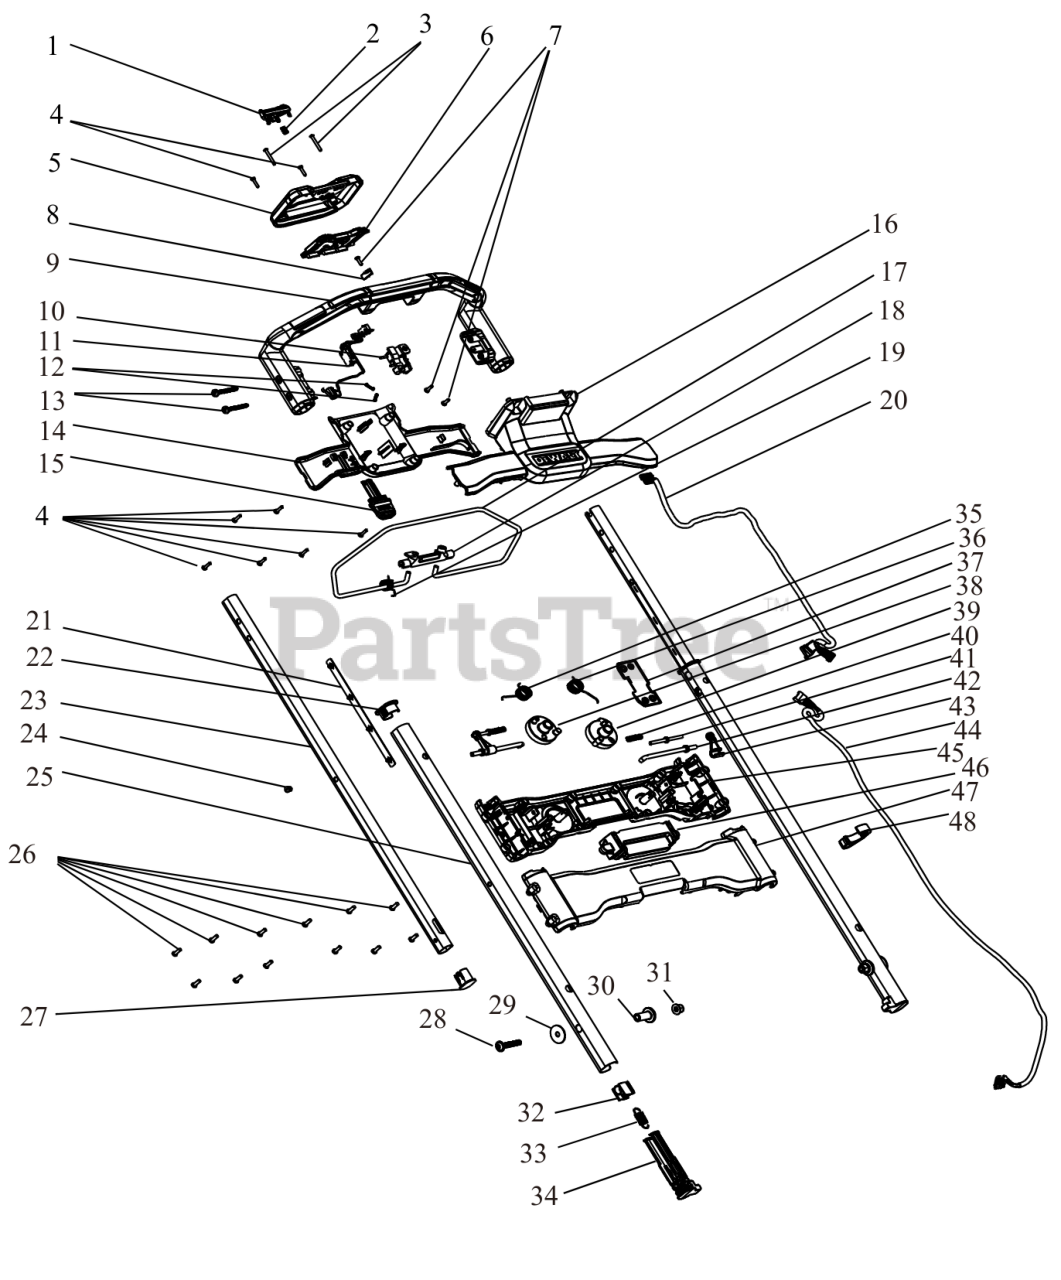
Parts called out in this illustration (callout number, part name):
1	BUTTON
2	SCREW
3	SPRING
5	COVER
6	CONTROL
8	BUTTOM
9	HANDLE SA
10	SWITCH
11	WIRE HARNESS
13	SCREW M6X45-T30-THD FRM
14	COVER
16	SWITCH COVER
17	CATCH
19	SPRING TORSION
20	WIRE HARNESS
21	STRIP
22	SLEEVE
23	TUBE UPPER
25	TUBE LOWER
26	SCREW M4.55X16 T20-PLAS THD FRM
27	SLEEVE
29	WASHER
30	SCREW
33	SPRING
35	SPRING
36	SPRING
37	COVER
40	SPRING
43	HOLDER
44	HARNESS
45	COVER
46	BUTTON
47	COVER
49	GRASSBAG
50	FRAME
51	CHUTE
54	SPACER
55	SCREW 1/4-10 x .750
56	SUPPORT
57	BRACKET
58	LOCK-NUT
61	SPRING
62	BRACKET
63	SUPPORT
64	BRACKET
65	SHIELD
66	INSERT
67	FLANGE LOCK NUT
68	WHEEL
69	AXLE REAR
70	SPRING
74	AXLE FRONT
76	WHEELS
77	PLATE
79	BLADE MOUNT
80	BLADE MOUNT
81	WASHER
83	PLATE
87	SPRING
88	MOTOR SA
89	PCB SA
90	BAFFLE
91	CONNECTOR
92	HARNESS
93	WIRE HARNESS
94	COVER
95	PLATE SA
97	HOUSING SA
100	COVER SA
101	BUSHING
102	COVER
103	SA HANDLE PNL KIT PUSH-BLACK
104	LABEL
866	20V BATTERY MAX XR 10AH DCB210
871	CHARGER
